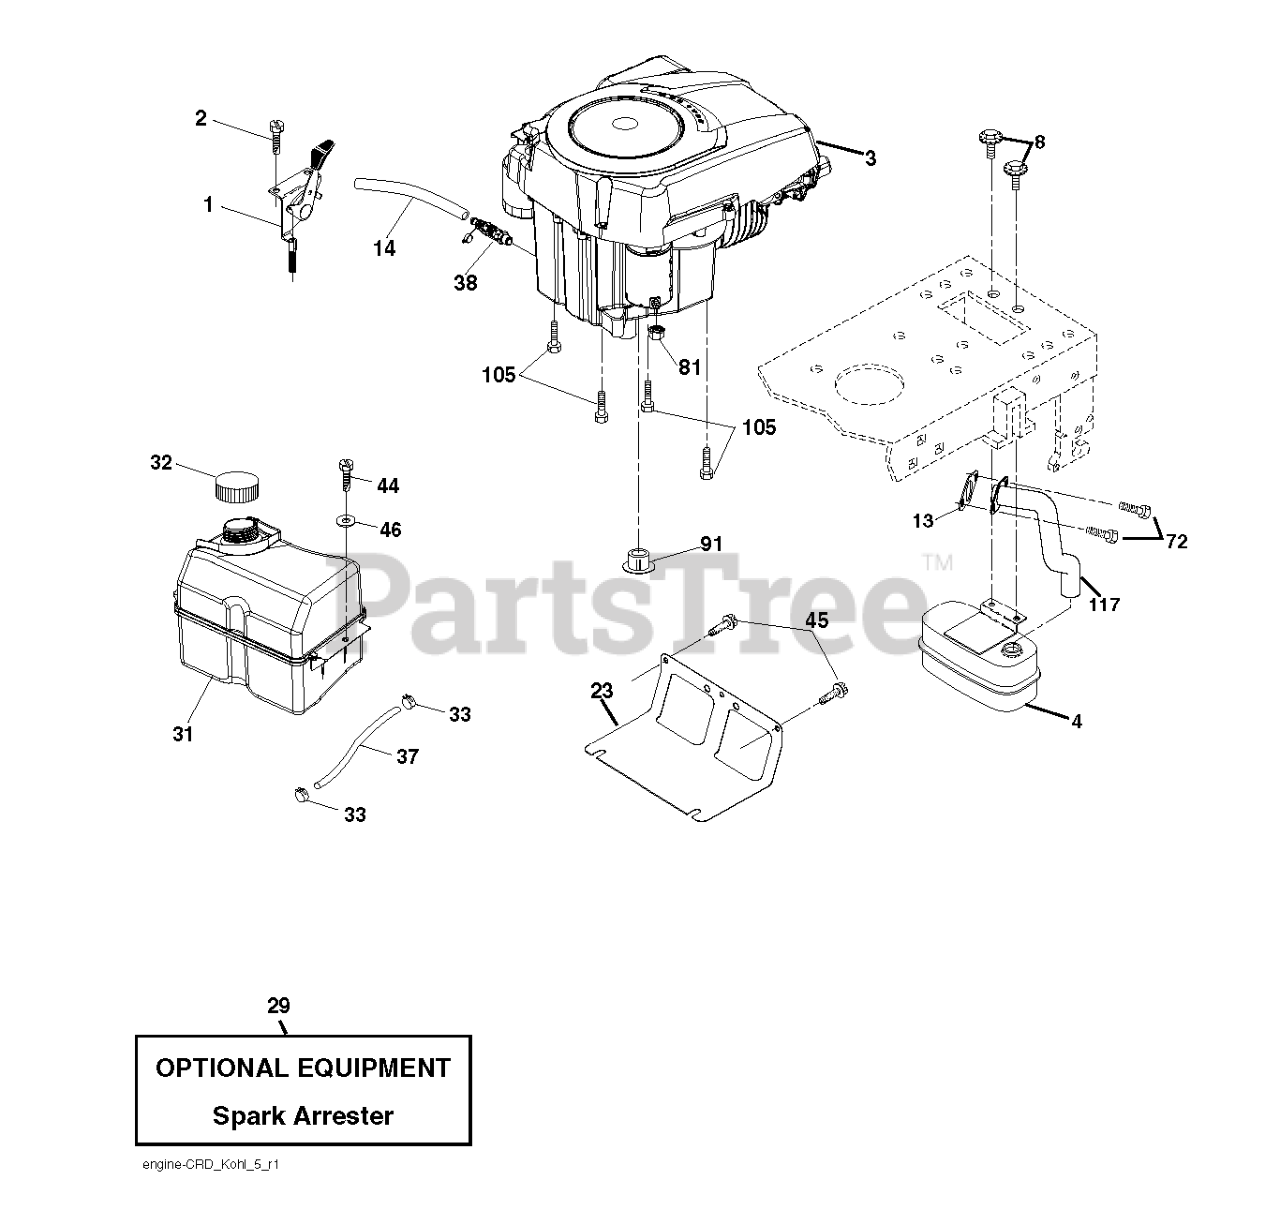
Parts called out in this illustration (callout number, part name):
1	CONTROL.TH/CK.C.
2	SCREW.#10 X 0.750.BOS
4	MUFFLER.SINGLE.CYL.KOHL/B&S
8	BOLT.5/16-18UNCX3/4 W/SEMS.BLK
13	GASKET.EXHAUST.KOHLER
14	TUBE, DRAIN OIL ASM.
23	SHIELD.BROWNING.DBR.GUARD
29	KIT.SPARK ARRESTOR 794945 B&S
31	RP TANK FUEL FRT 1.5 GAL
32	CAP.FUEL.2.25"VENTED"
33	HOSE CLAMP
37	LINE.FUEL.20
38	VALUE.OIL.DRAIN
44	SCREW HEXWSHR 1/4-20X3/4
45	SCREW, 3/8-16X3/4
79	SCREW.SOCKET HD.5/16-1
81	NUT
91	BUSHING.1.375OD
105	SCREW 3/8-16X1
117	RP.TUBE.EXHAUST.KOHL.COURAGE
